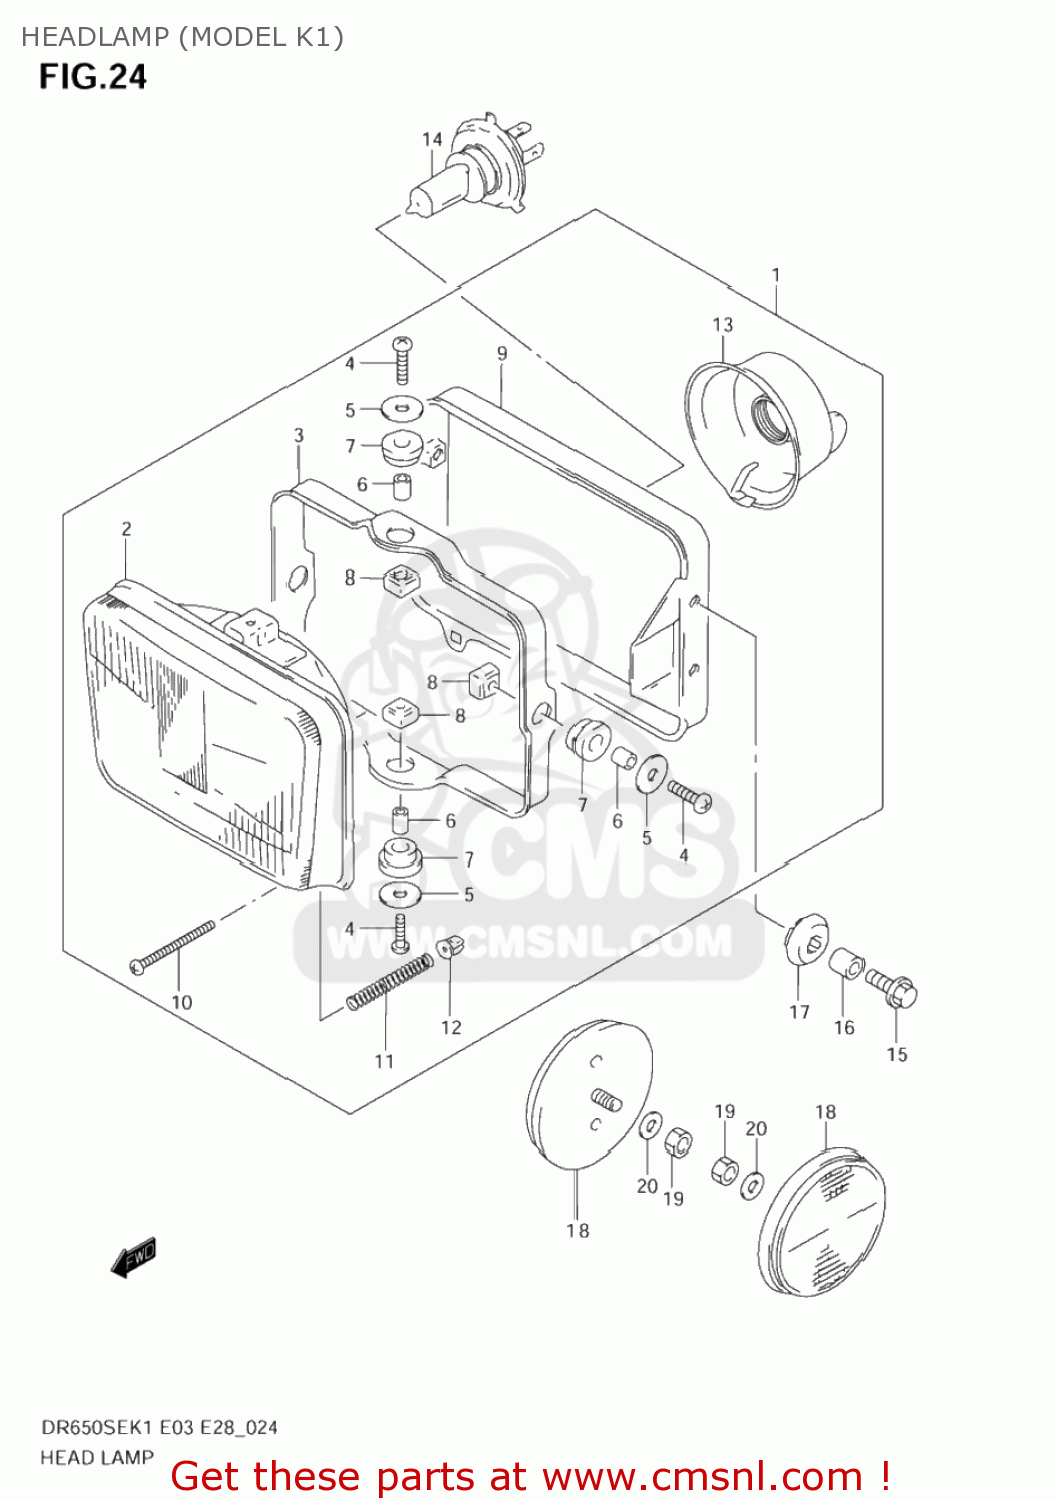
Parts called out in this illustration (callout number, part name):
1	HEADLAMP ASSEMBLY
2	UNIT ASSY
3	RING,MOUNTING
4	SCREW
5	WASHER(5.5X18X1)
6	SPACER
7	CUSHION
8	NUT
9	HOUSING
10	SCREW(4X45)
11	SPRING,ADJUSTING
12	NUT,ADJUSTING
13	COVER,SOCKET
14	BULB(12V60/55W,H4)
15	BOLT(6X20)
16	SPACER(6.5X10X10)
17	CUSHION
18	REFLECTOR,REFLEX
19	NUT
20	LOCK,WASHER
